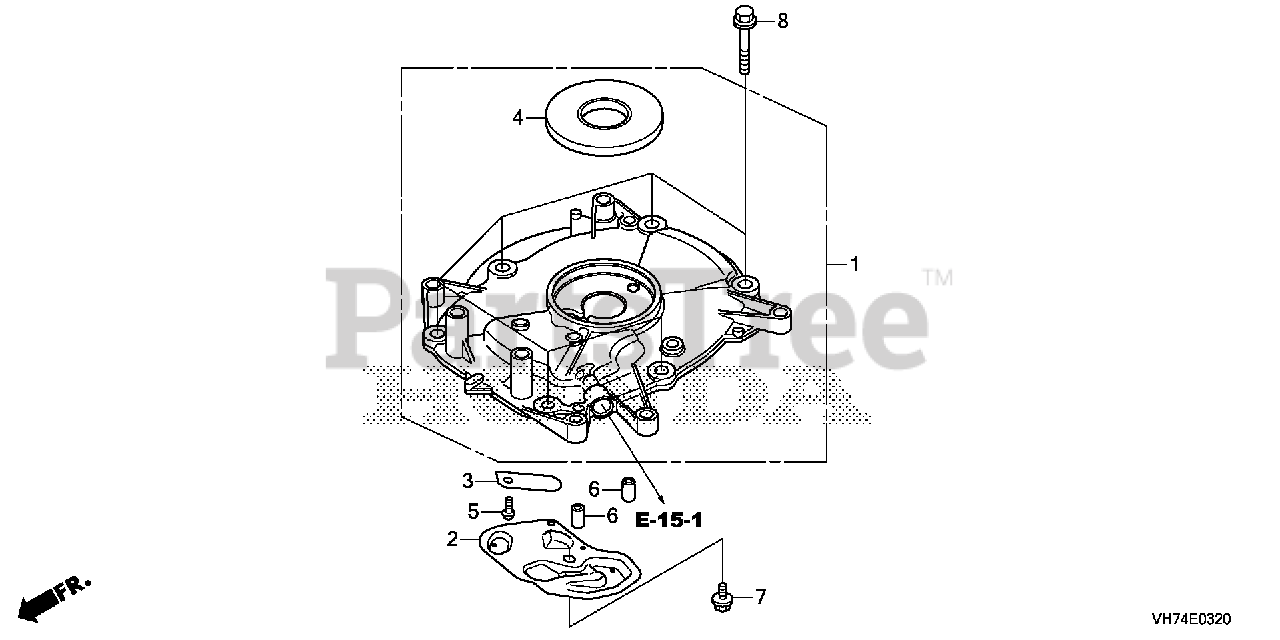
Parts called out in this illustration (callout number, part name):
1	COVER ASSY., CRANKCASE
2	COVER, BREATHER
3	PLATE, VALVE
4	OIL SEAL (25.4X62X6)
4	OIL SEAL (25.4X62X6) (FRG-NOK)
5	SCREW, PAN (5X8)
6	PIN A, DOWEL (8X14)
7	BOLT, FLANGE (6X14)
8	BOLT, FLANGE (8X25)
